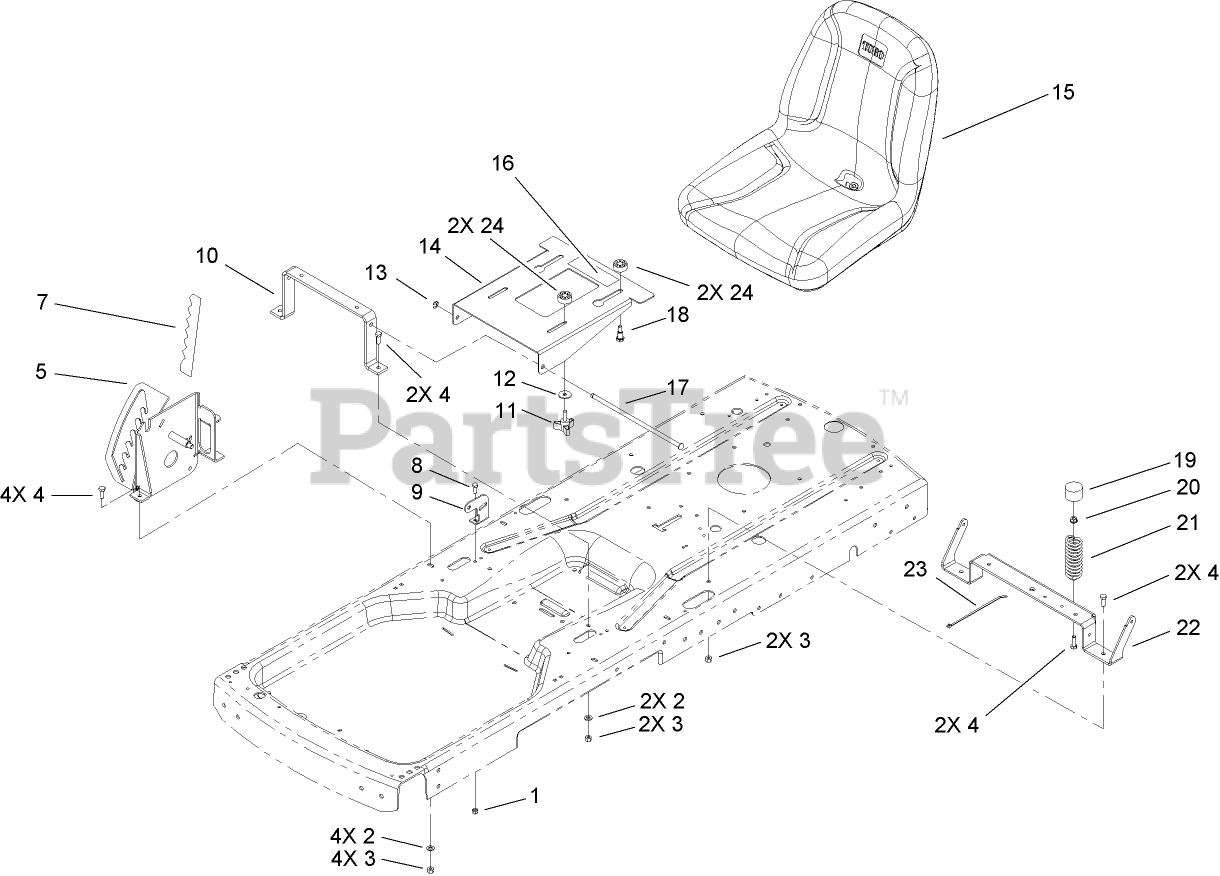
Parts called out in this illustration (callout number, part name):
1	NUT-LOCK, NI
2	WASHER-PLAIN
3	NUT-LOCK, NI
4	SCREW-HH
5	RH PLATE ASM
7	DECAL-HOC
8	SCREW-HH
9	BRACKET-BELLCRANK
10	BRACE-SEAT, FRONT
12	WASHER-PIVOT
13	E-RING
14	BRACKET-SEAT
15	SEAT
16	DECAL-SERVICE, CE
17	PIN-PIVOT
18	SCREW-SHOULDER
19	CAP-PROTECTOR
20	NUT-HF
21	SPRING-COMPRESSION
22	BRACE-SEAT, REAR
23	TIE-CABLE
24	SPACER-NYLON
